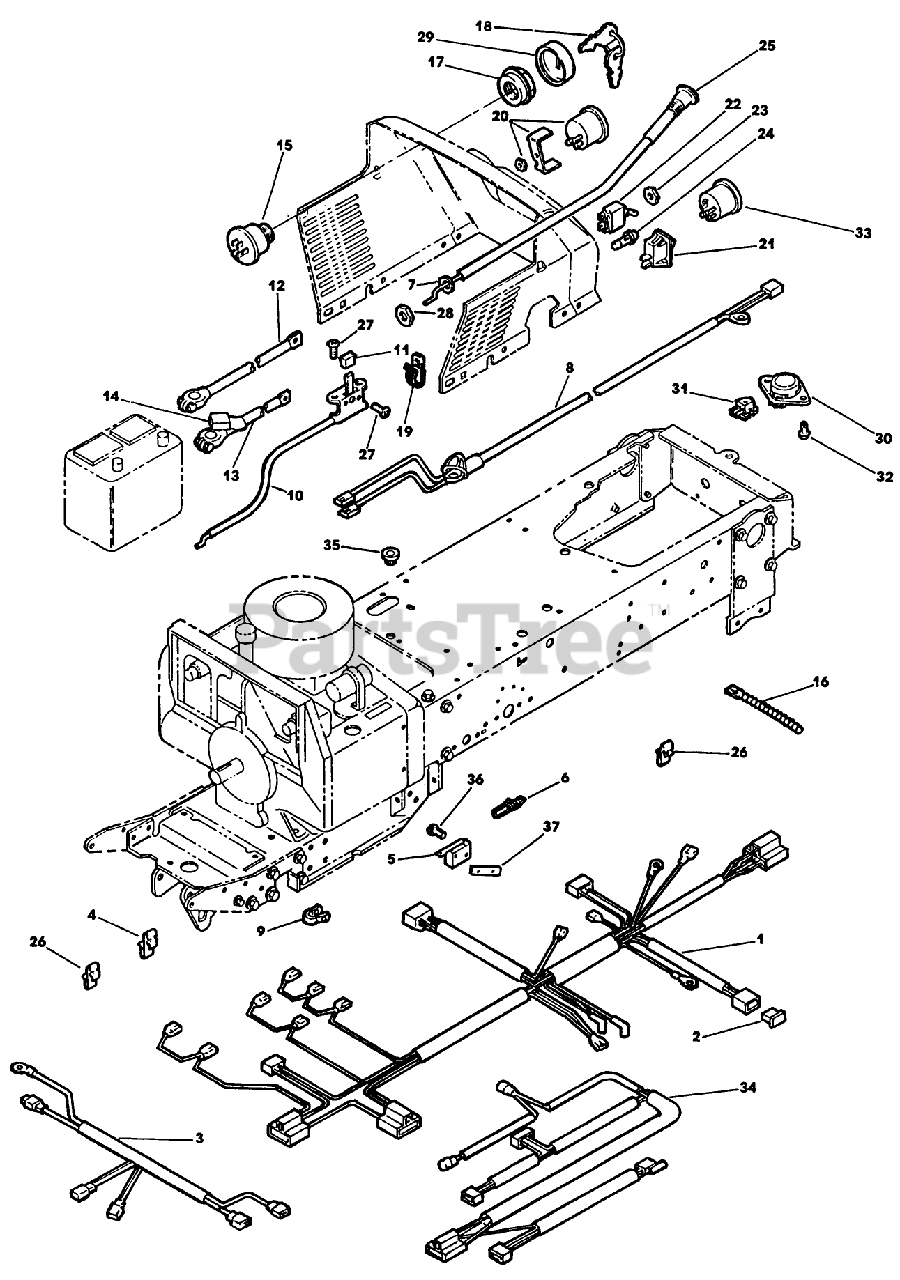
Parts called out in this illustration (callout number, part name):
4	CLIP
7	WASHER
10	CONTROL - THROTTLE
11	THROTTLE KNOB
17	NUT
18	KEY
21	SWITCH ASSEMBLY
22	SWITCH-PTO W/SAFTY
24	LIGHT-PTO INDICTOR
25	CONTROL - CHOKE
26	CLIP-RETAINER, WIRE
28	NUT-HEX
29	BEZEL
30	SWITCH,SEAT
31	SWITCH
